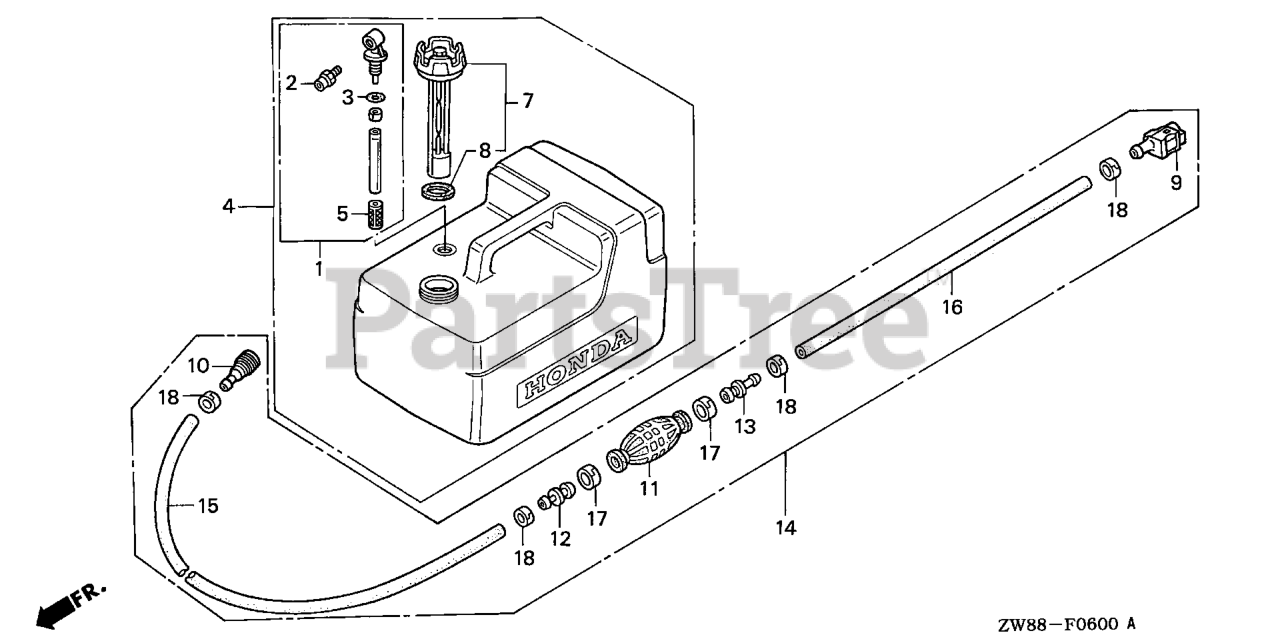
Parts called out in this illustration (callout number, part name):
1	JOINT ASSY., FUEL
2	FITTING, QUICK DISCONNECT Use from Frame SN 1205705.
3	O-RING Use up to Frame SN 1300961.
4	TANK ASSY., FUEL Use from Frame SN 1000337.
4	TANK ASSY., FUEL
5	FILTER, FUEL
7	CAP, FUEL FILLER
8	GASKET, FUEL CAP
9	CONNECTOR ASSY., FUEL (A)
10	CONNECTOR, FUEL (CONNECTOR TYPE)
11	BULB, PRIMER
12	VALVE, IN.
13	VALVE, OUTLET
14	TUBE ASSY., FUEL
15	TUBE, FUEL LONG (7.3X2000) (CONNECTOR TYPE)
16	TUBE, FUEL SHORT (6.3X500) (CONNECTOR TYPE)
17	BAND, TUBE CLIP (20MM)
18	BAND, TUBE CLIP (12.5MM)
